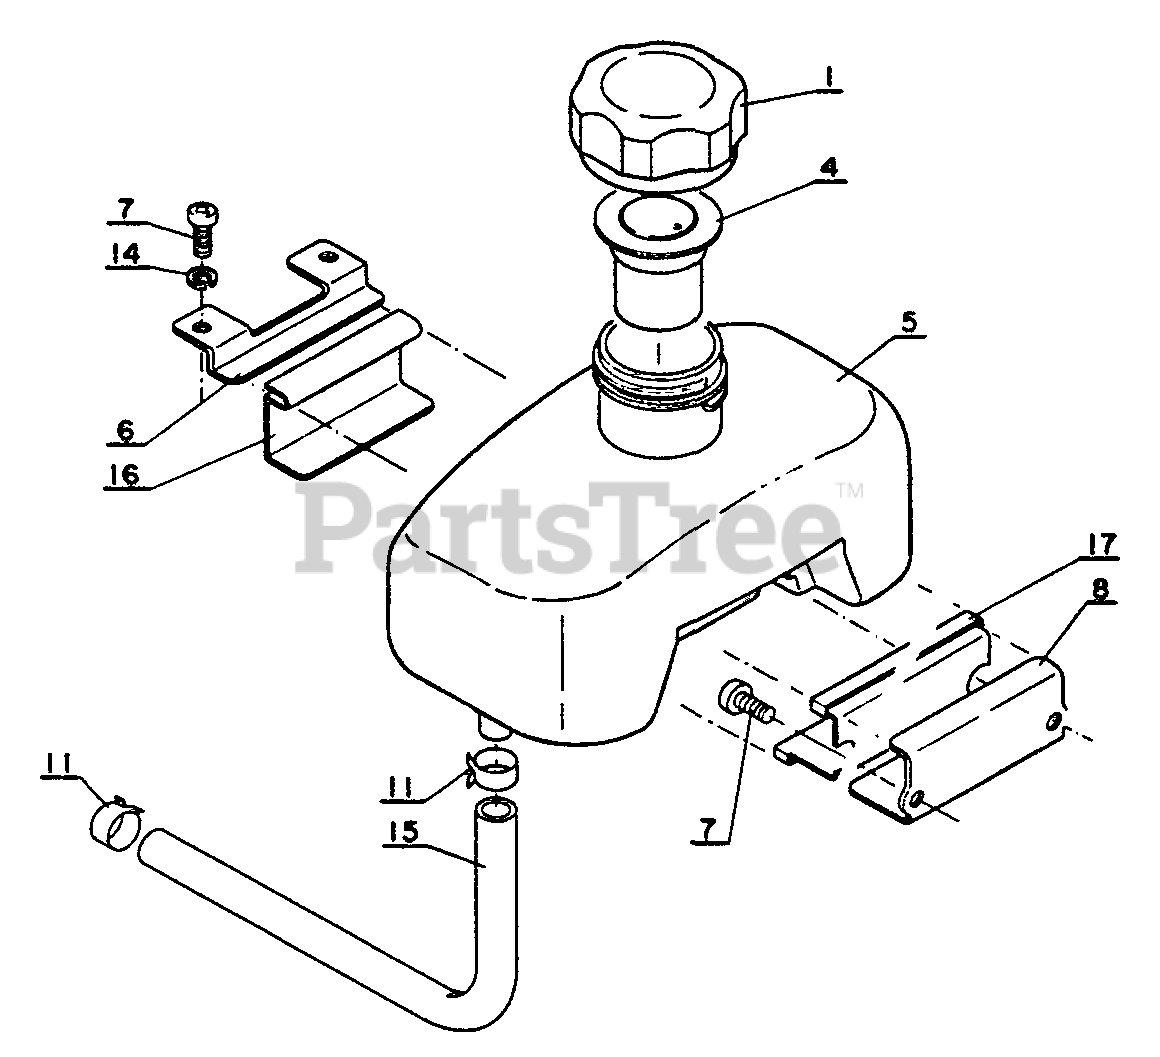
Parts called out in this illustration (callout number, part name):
1	CAP
4	VENT, CAP
5	TANK, FUEL
6	BRACKET, FUEL TANK
7	SCREW - 4X8
8	BRACKET, FUEL TANK
11	CLAMP
14	LOCKWASHER - 4
15	PIPE - FUEL
16	CUSHION, FUEL TANK
17	CUSHION, FUEL TANK
